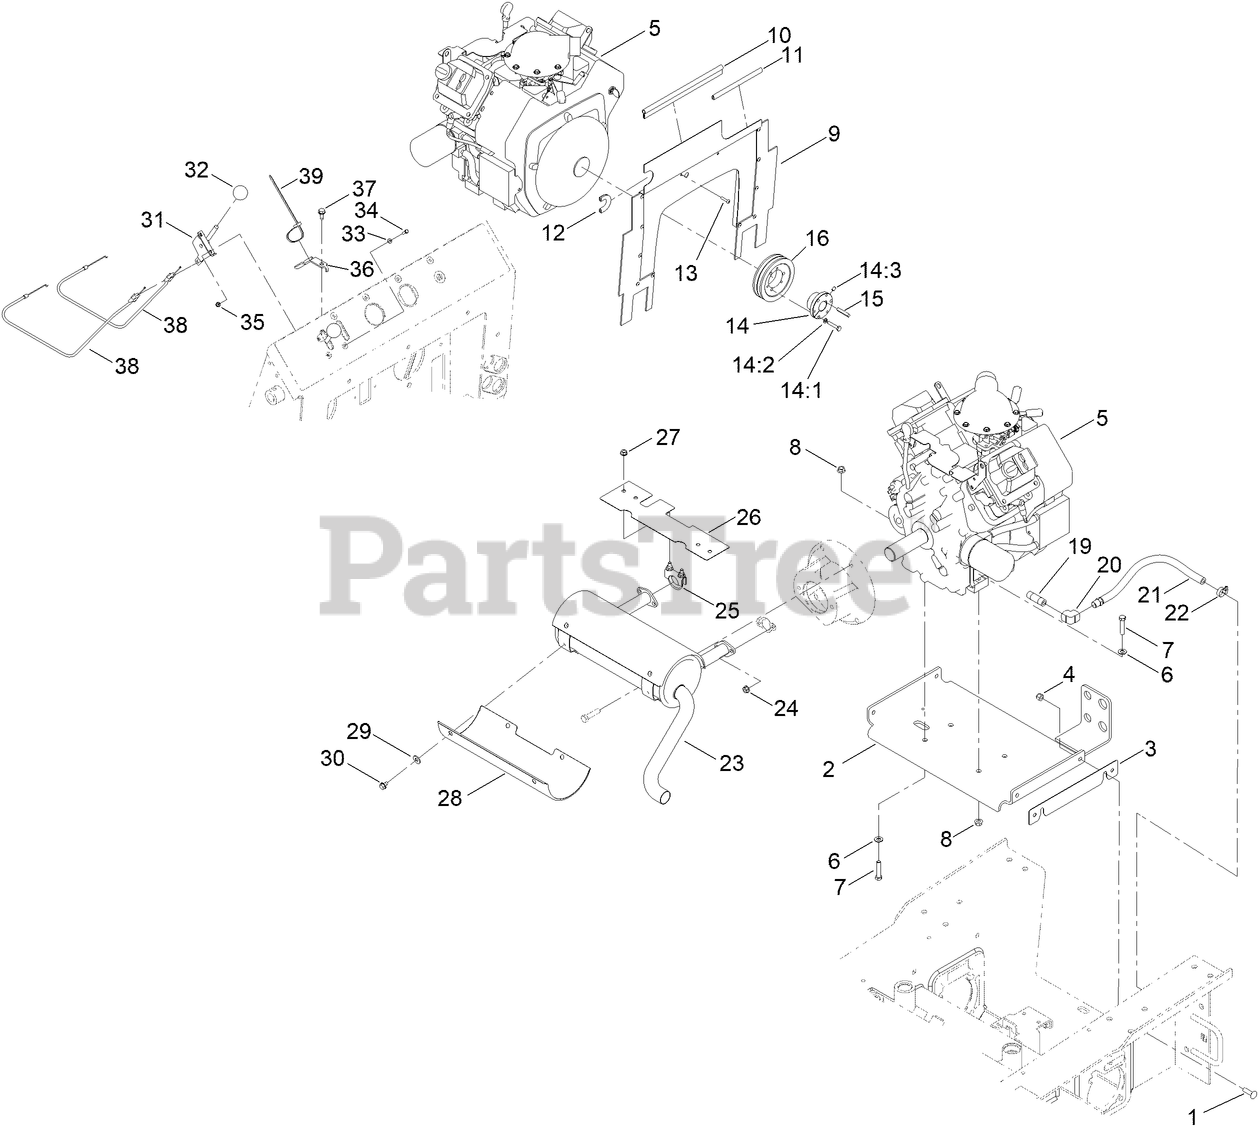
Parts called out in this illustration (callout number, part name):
1	SCREW-CARR
2	PLATE-MOUNTING, ENGINE
3	SHIM-STRAP
4	NUT-LOCK, NI
6	WASHER-PLAIN
7	SCREW-HH
8	NUT-HF
9	BAFFLE-ENGINE
10	STRIP-SEAL, 10.5 INCH
11	SEAL-STRIP, 6.5 INCH
12	SEAL-STRIP, 3 INCH
13	SCREW-PPH
14	BUSHING
14:1	SCREW-HH
14:2	WASHER-LOCK
14:3	SCREW-SET, HSH
15	KEY-SQUARE
16	PULLEY
19	NIPPLE
20	ELBOW-90 DEG
21	OIL HOSE ASM
22	CLAMP-HOSE
23	MUFFLER
24	NUT-HF
25	Clamp-Muffler
26	SHIELD-MANIFOLD
27	NUT-HF
28	SHIELD-MUFFLER
29	WASHER-FLAT
30	SCREW
31	LEVER-CONTROL
33	WASHER-FLAT
35	NUT-KEPS
36	GUIDE-CABLE
37	SCREW-THD ROLL, HWH
38	CABLE-THROTTLE/CHOKE
39	TIE-CABLE
